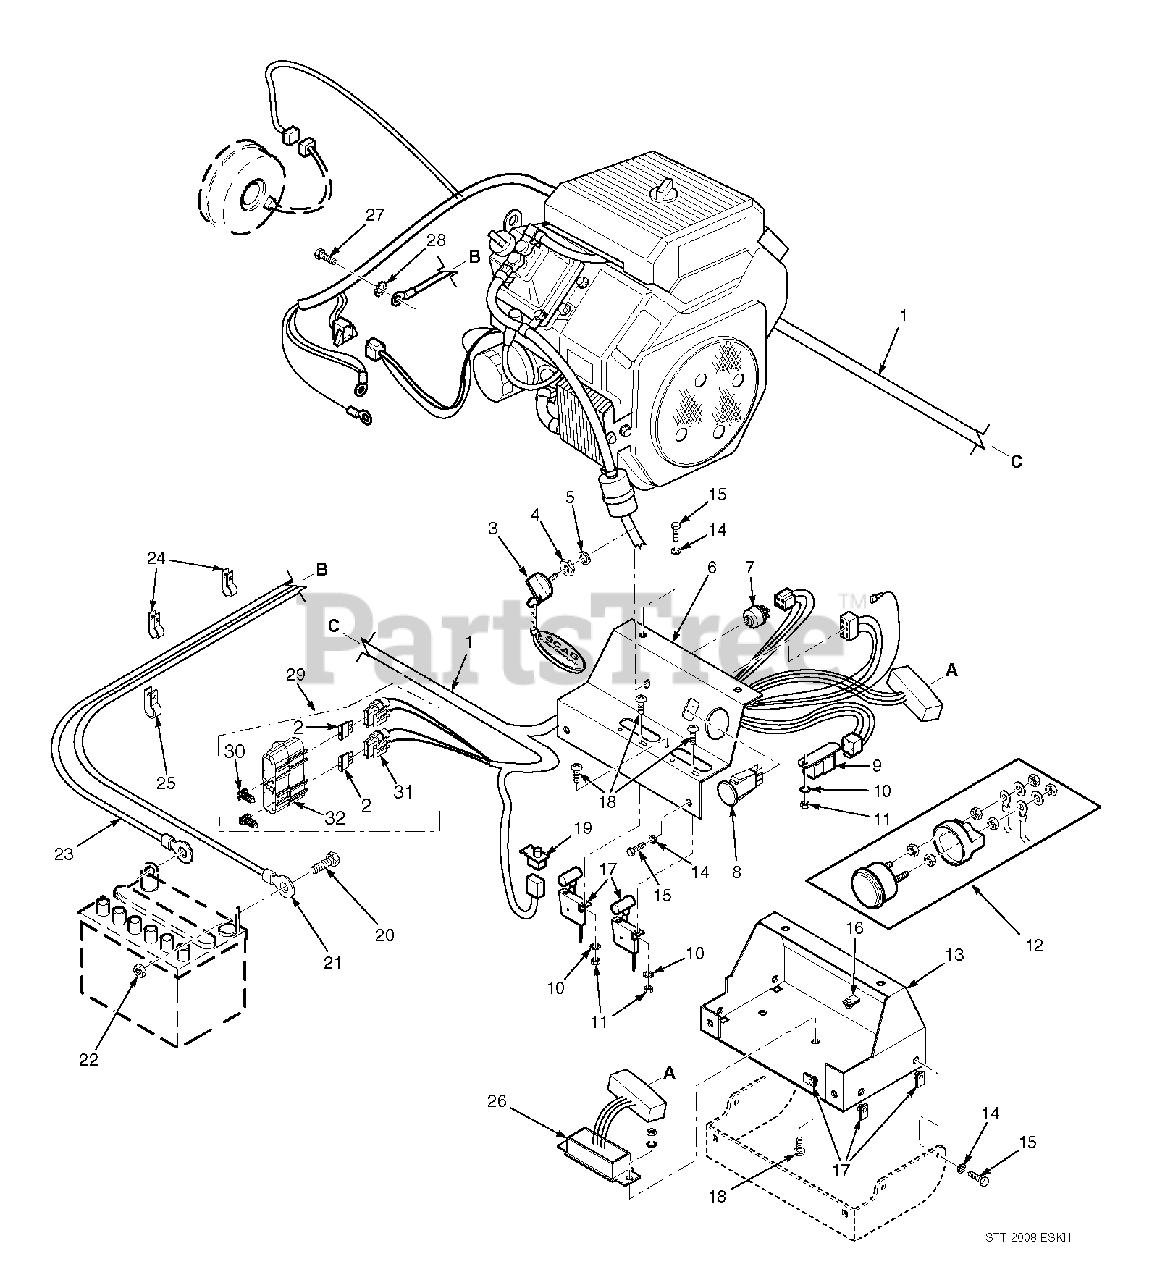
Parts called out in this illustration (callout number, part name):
1	Wire Harness, STT Air-Cooled
2	Fuse, 20 AMP
3	Key, Ignition
4	Nut, Hex 5/8-32
5	Lockwasher, 5/8" Internal
6	Instrument Panel, Top w/Decals
7	Key Switch
8	Switch, PTO
9	Relay
10	Lockwasher, #10 External Tooth
11	Nut, Hex #10-32
12	Ammeter
13	Base, Instrument Panel
14	Lockwasher, 1/4"
15	Bolt, Hex Head 1/4-20 x 3/4"
16	U-Nut, 1/4-20
17	Throttle And Choke Controls
18	Screw, Phillips Washer Head #10-32 x 1/2"
19	Switch, Interlock-Seat
20	Bolt, Hex Head 1/4-20 x 1/2"
21	Cable, Battery - Red
22	Nut, Hex 1/4-20
23	Cable, Battery - Black
24	Clamp, Cable 1/2" ID.
25	Clamp, Cable 3/4" ID.
26	Electronic Module
27	Bolt, Hex Head M8-1.25 x 20mm
28	Lockwasher, 5/16" External Tooth
29	Double Fuse Assembly, Sealed
30	Clip, Wire
31	Fuse Holder
32	Cover, Sealed Double
